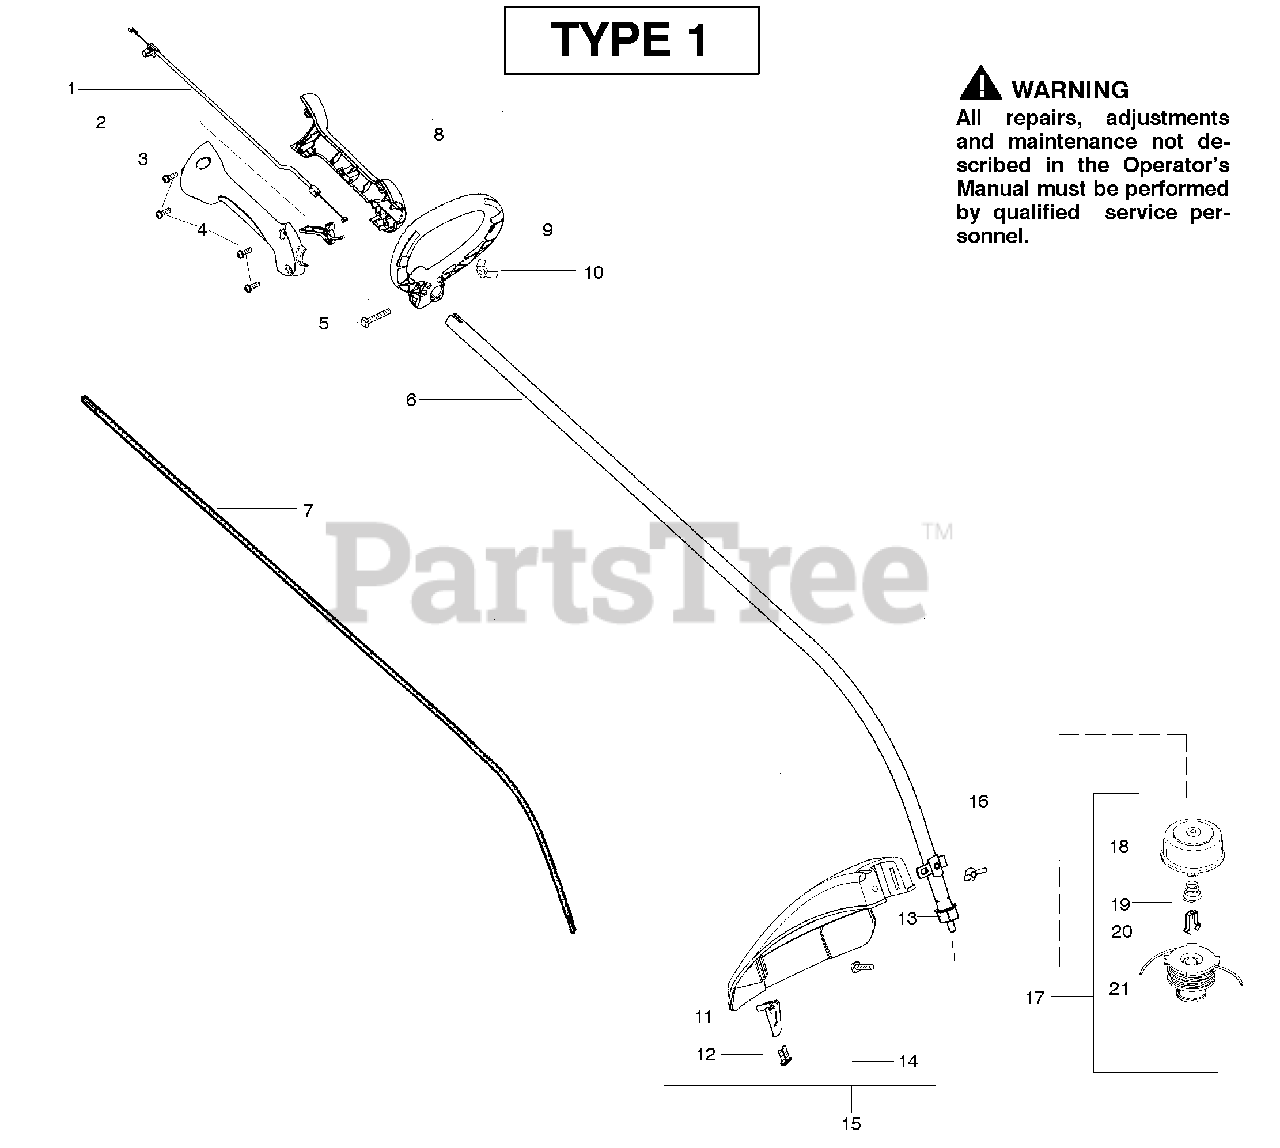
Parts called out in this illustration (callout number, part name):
1	Assy-Throttle Cable
3	Throttle Hsg. (Right)
4	Screw-Throttle Hsg.
5	Bolt-Handle/Shield
6	Assy-Drive Shaft Hsg.
7	Shaft- Flex
8	Throttle Hsg. (Left)
9	Assy-Handle
10	Wingnut
11	Line Limiter
12	Screw-Line Limiter
13	Dust Cup
15	Kit-Shield Assy
16	Wingnut
17	Accy-TNG VI Cutting Head
18	Assy-Hub
19	Spring-Compression
20	Clip-Retainer-Head
21	Accy- Spool w/Line
